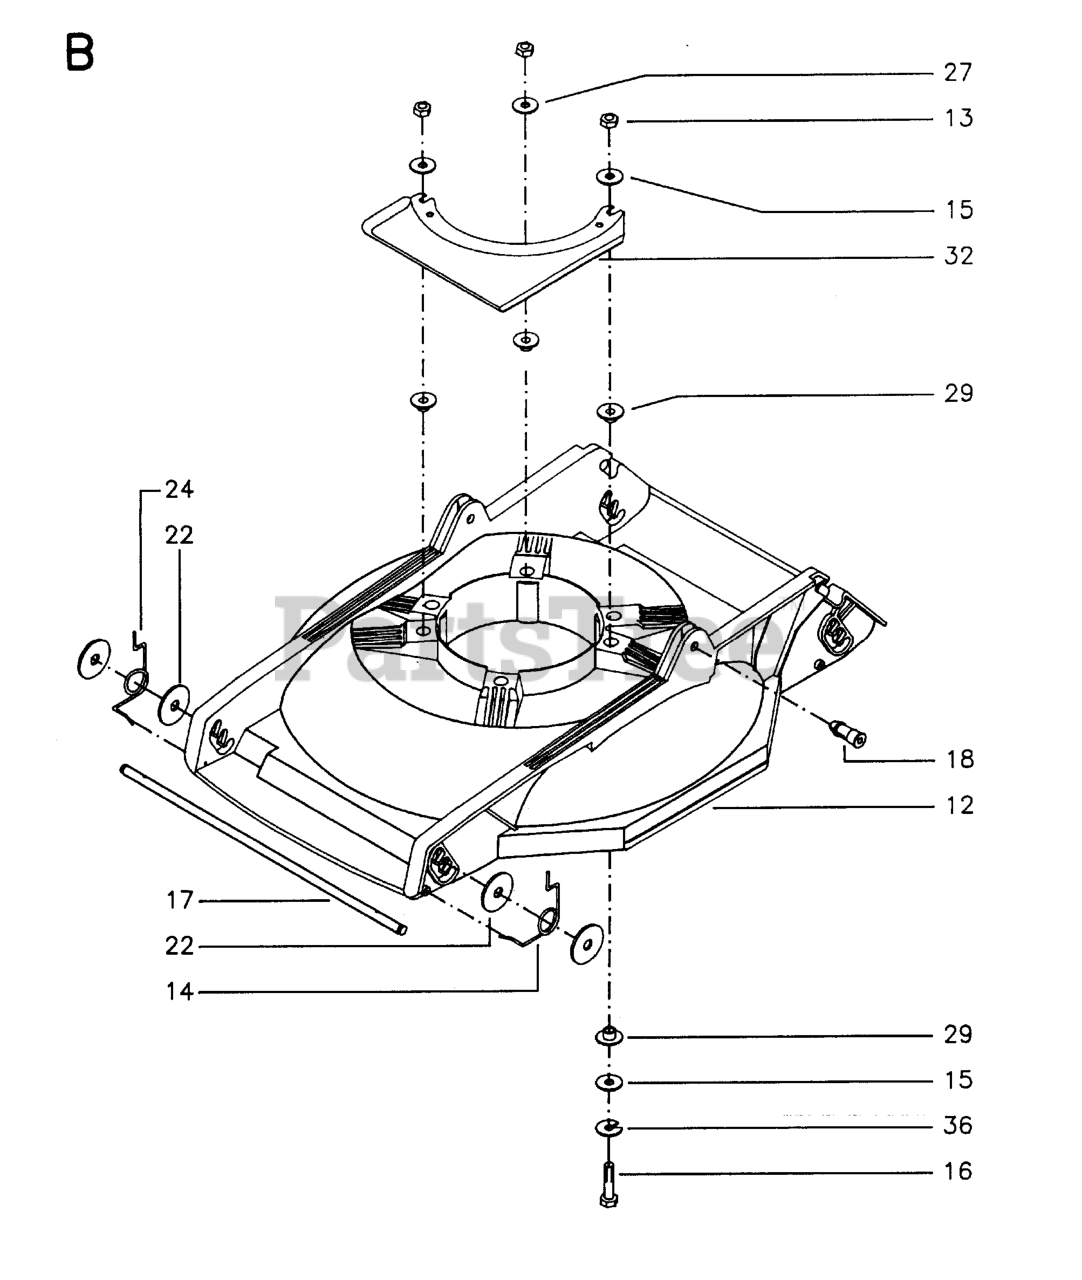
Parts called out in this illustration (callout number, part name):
13	LOCKNUT M8
29	FLANGE BRG.
36	SPRING WASHER
